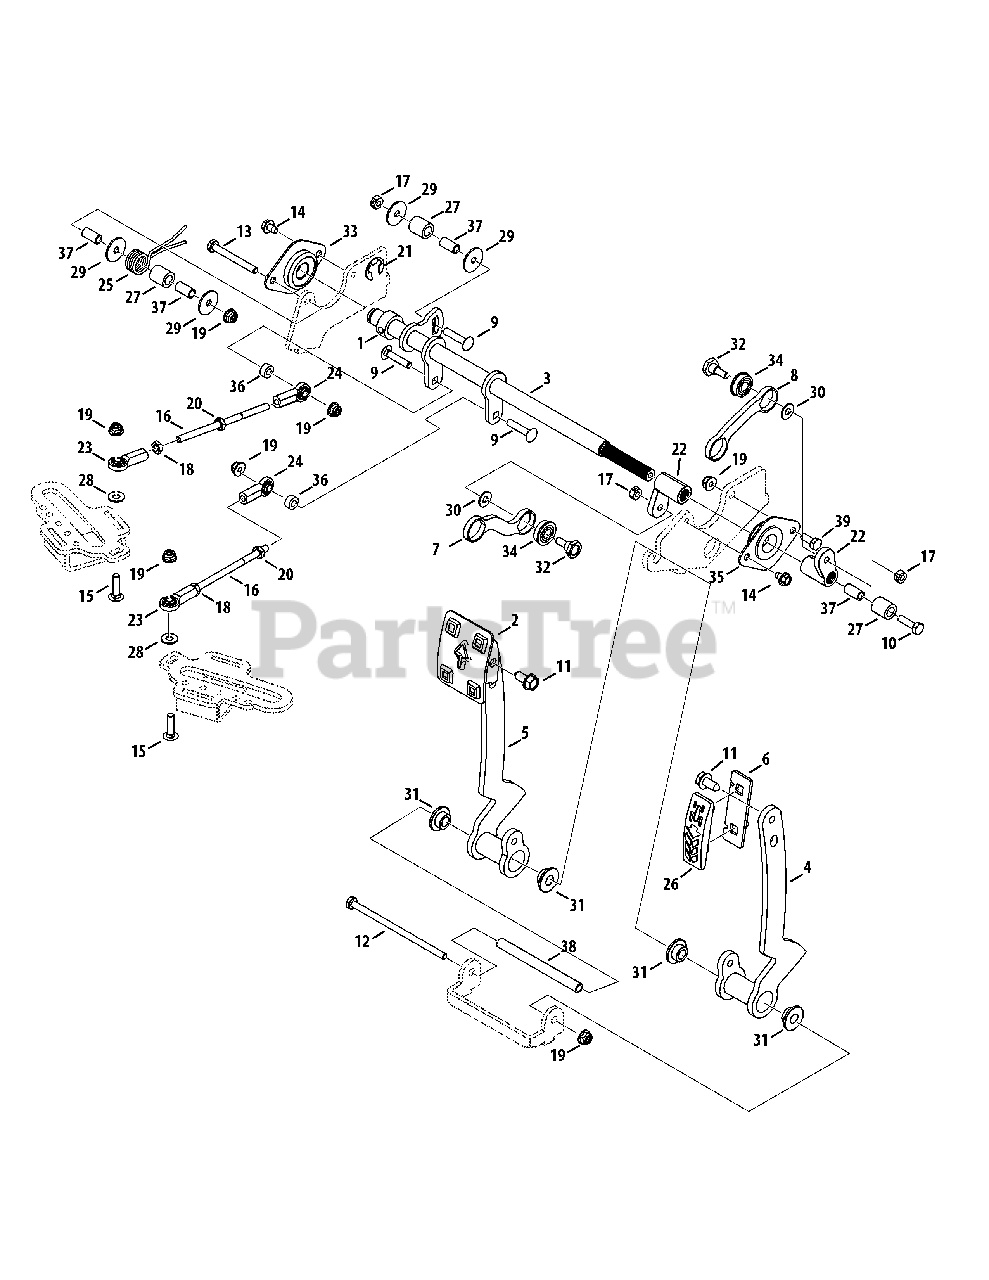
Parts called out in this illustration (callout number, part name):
1	Shaft Collar, .625 x 1.0 x .438
2	Forward Pedal Assembly
3	Speed Control Arm Assembly
4	Reverse Pedal Assembly
5	Forward Pedal Assembly
6	Reverse Pedal Bracket
7	Forward Pedal Link
8	Reverse Pedal Link
9	Carriage Screw, 1/4-20 x 1.25
10	Hex Cap Screw, 1/4-20 x 1.25
11	Screw, 5/16-18 x .750
12	Hex Cap Screw, 1/4-20 x 5.00
13	Hex Cap Screw, 1/4-20 x 2.25
14	Screw, 1/4-20 x .375
15	Carriage Screw, 1/4-20 x 1.00
16	Speed Control Link Rod
17	Nut, 1/4-20, Hexlock
18	Jam Nut, 1/4-28
19	Nut, 1/4-20, Flangelock
20	Jam Nut, 1/4-28, LH
21	E-Ring, .625
22	Pedal Shaft Arm
23	Rod End, 1/4-28
24	Rod End, 1/4-28, LH
25	Torsion Spring, .70 ID
27	Spacer, .385 x .625 x .700
28	Washer, .250 x .630 x .052
29	Washer, .255 x 1.00 x .060
30	Washer, .271 x .630 x .065
31	Shoulder Spacer, .38 x .62 x 1.00
32	Shoulder Screw, .375 x .280, 1/4-20
33	Ball Bearing, .625
34	Bearing, .375 x .875 x .281
35	Ball Bearing, .750
36	Spacer, .256 x .500 x .240
37	Spacer, .260 x .375 x .75
38	Spacer, .255 x .375 x 4.28
39	Hex Cap Screw, 1/4-20 x .75
